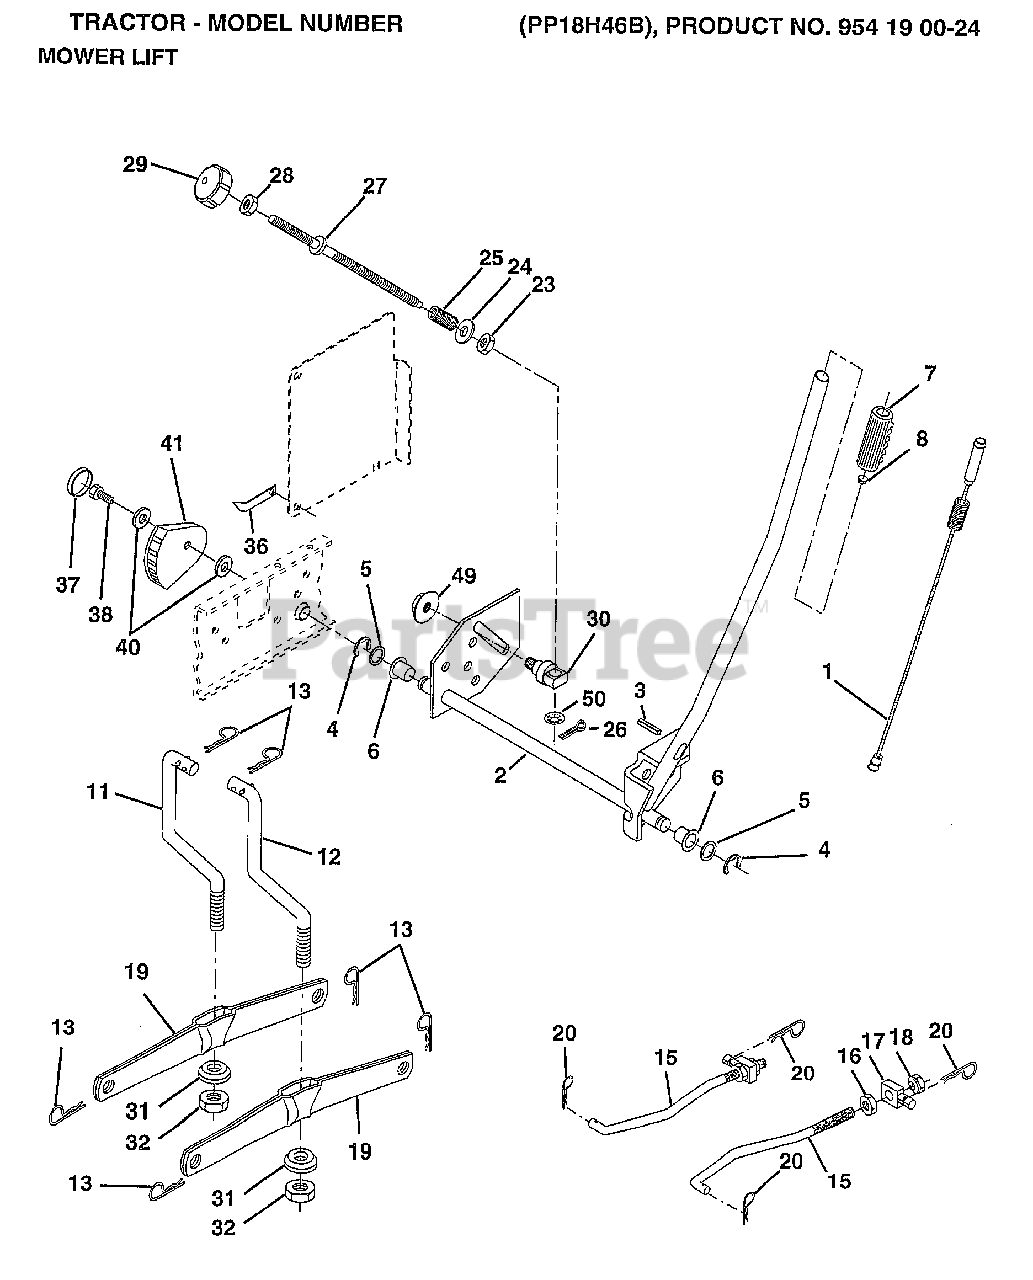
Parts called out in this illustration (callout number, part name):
1	WIRE ASM W.SPRING
2	"SHAFT ASM LIFT,RH"
3	PIN-GROOVE LT
5	WASHER
6	NYLON BEARING
7	GRIP
15	LINK.FRONT
16	NUT
17	TRUNION
18	NUT LTV
19	ARM SUSP REAR
20	RETAINER SPRING
23	NUT T
24	WASHER
25	SPRING T
28	NUT
29	KNOB INF 3/8-16
30	TRUNNION
31	BEARING PVT LH
32	NUT.CROWNLOCK.3/8
36	POINTER-INDICAT
37	"PLUG,HOLE"
38	SCREW
40	WASHER
41	INDICATOR HEIGHT
49	NUT.HXFLG.LOCK.
50	NUT PUSH M
